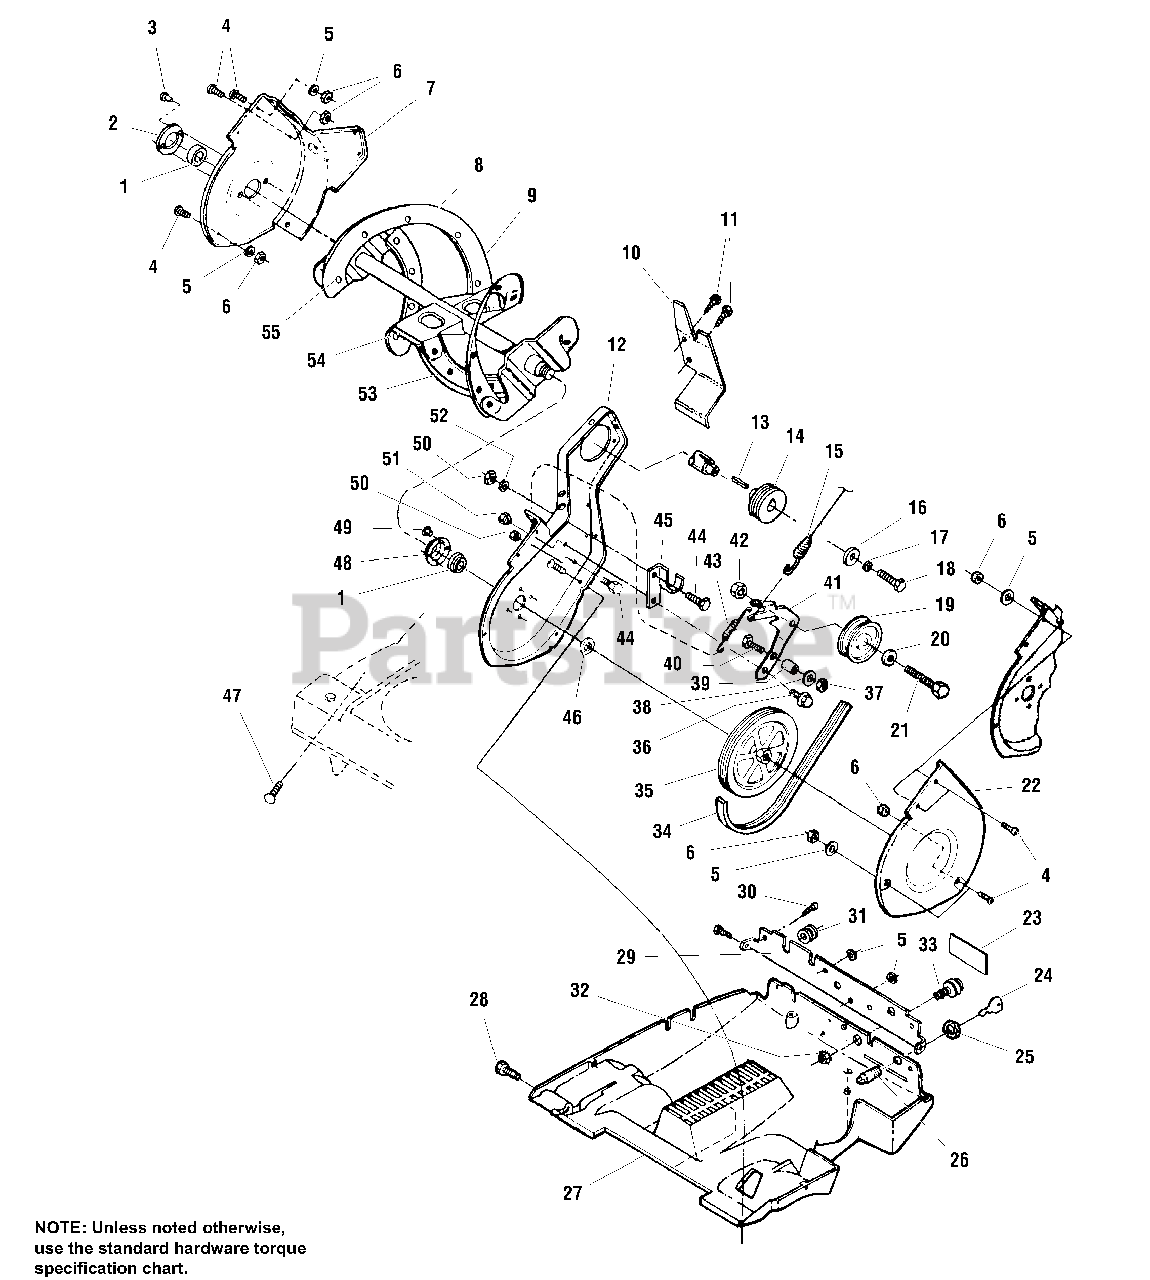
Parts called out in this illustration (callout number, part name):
1	BALL BEARING, Auger Axle
2	RETAINER, Ball Bearing
4	SCREW, Phillips, #10-24 x 5/8
5	WASHER, Retaining
6	NUT, #10-24
7	FRAME, Right Side
8	KIT, Auger Flighting
9	AUGER, Complete Assembly
10	SHIELD, Belt
11	SCREW, Tap, #10-24 x 1/2
12	FRAME, Left Side
13	KEY, 3/16 Sq. x 1
14	PULLEY, Drive
15	CABLE, Auger Control
16	WASHER, Flat
17	WASHER, Split Lock, 5/16
18	BOLT, Hex, 5/16-24 x 7/8, Gr. 5
19	PULLEY, Idler
20	WASHER, Flat 3/8
21	BOLT, Hex, 3/8-16 x 1-1/2
22	GUARD, Belt
23	DECAL, Choke
24	KEY, Ignition
25	NUT, Hex, Ignition Switch, 5/8-32
26	SWITCH, Ignition
27	COWLING, Lower
28	SCREW, Hex, 1/4-20 x 5/8
29	BRACKET, Control Panel
30	SCREW, Hex, 1/4-20 x 5/8
31	GROMMET, Metal
32	NUT, Keps, 1/4-20
33	PRIMER, Bulb
34	BELT, Drive
35	PULLEY- Drive
36	BOLT, Idler Pivot
37	NUT, Center Lock, 1/4-20
38	WASHER, Internal Tooth, 5/8
39	ROLLER, Belt Stop
40	BOLT, Hex, 1/4-20 x 1
42	NUT, Serrated, Flange Lock, 3/8
43	SPRING, Extension
44	BOLT, Hex, 1/4-20 x 3/4
45	BRACKET, Belt
47	CARRIAGE BOLT, 1/4-20 x 3/4
48	RETAINER, Bearing
49	RIVET, 1/4
50	NUT, 1/4-20, Nylock
51	NUT, Nylock, 5/16-18
52	WASHER, Flat, 1/4
53	PEDAL, Auger
54	BLADE, Auger
55	RIVET, Truss
